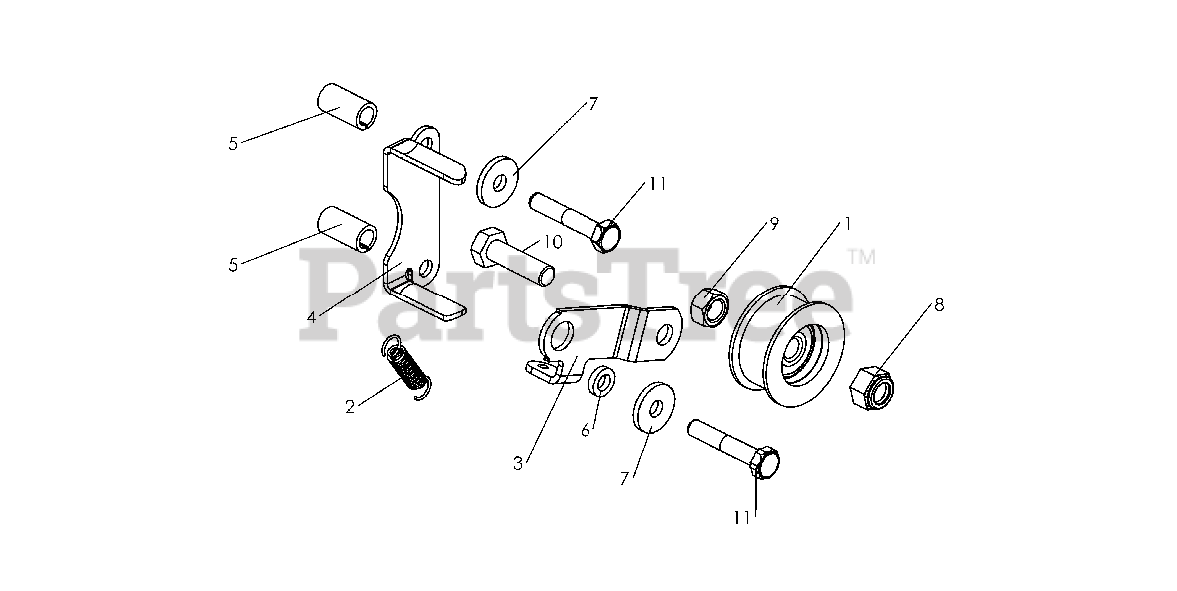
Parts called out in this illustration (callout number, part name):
1	PULLEY
7	WASHER
8	NUT
9	NUT
10	SCREW
